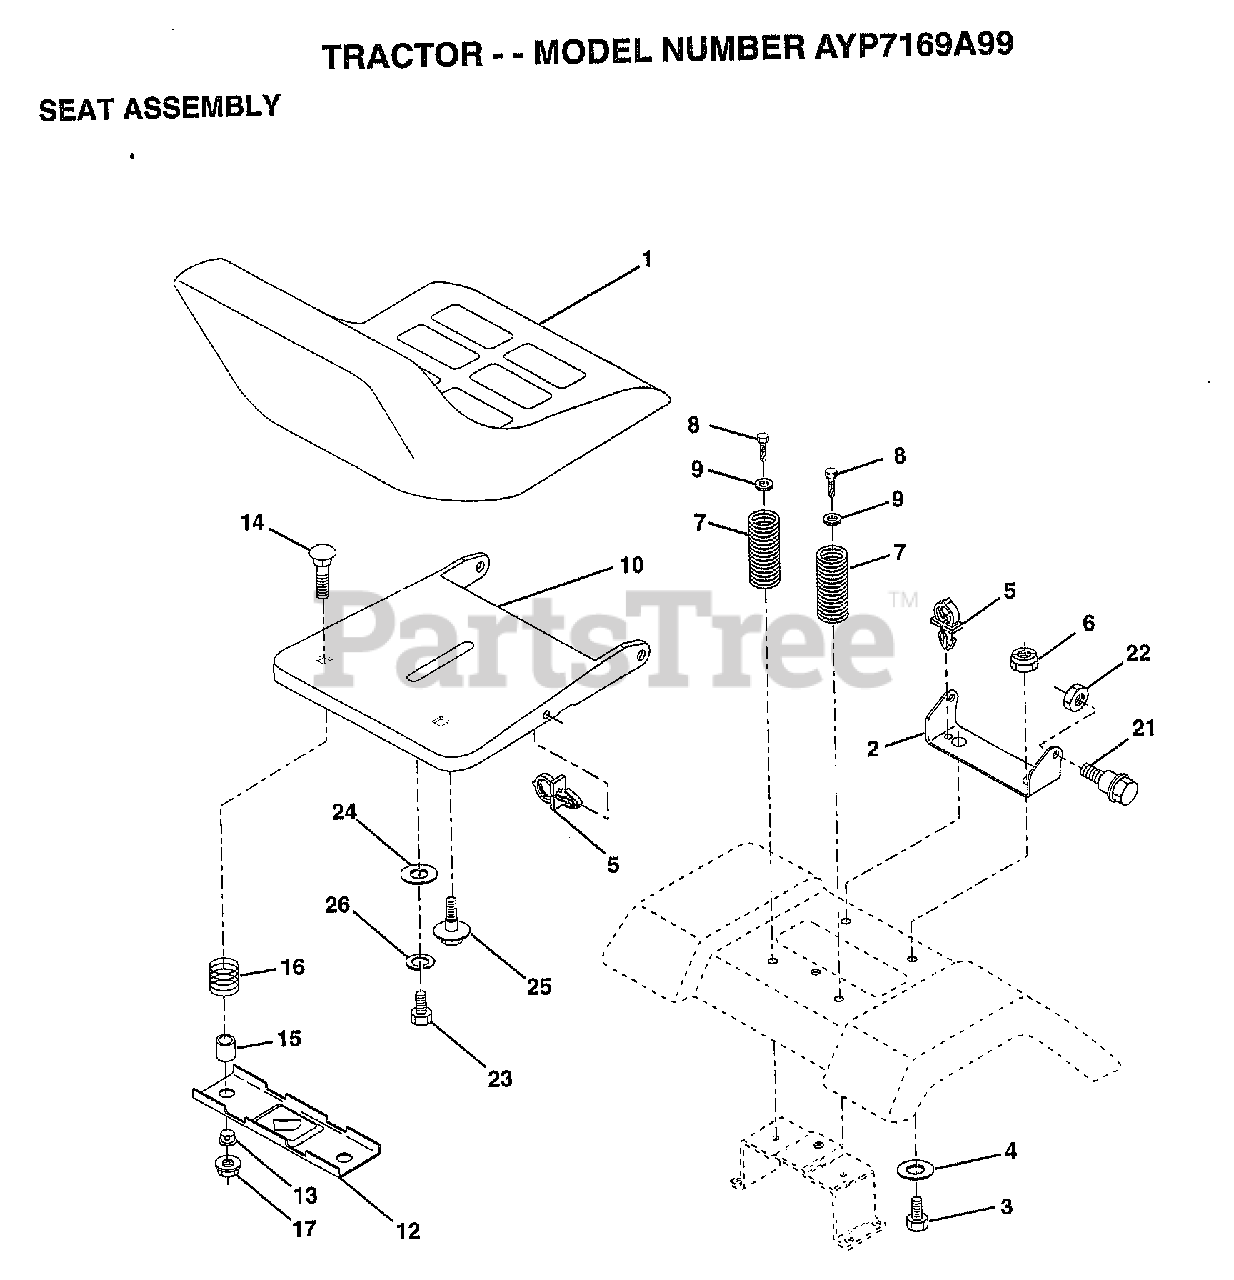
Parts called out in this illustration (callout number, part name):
2	BRACKET PVT SEAT
3	BOLT
4	WASHER PM
5	CLIP.PUSH-IN.HING
6	NUT
7	SPRING COMPRESSIO
8	SCREW GTV
9	WASHER
10	PAN-SEAT
12	BRKT SWITCH
13	BUSHING
14	BOLT-RD HD SQ NK
15	SPLIT SPACER
16	SPRING
21	"BOLT,SHOULDER"
22	NUT
23	BOLT
24	WASHER
25	"BOLT,SHOULDER"
26	LOCKWASHER
